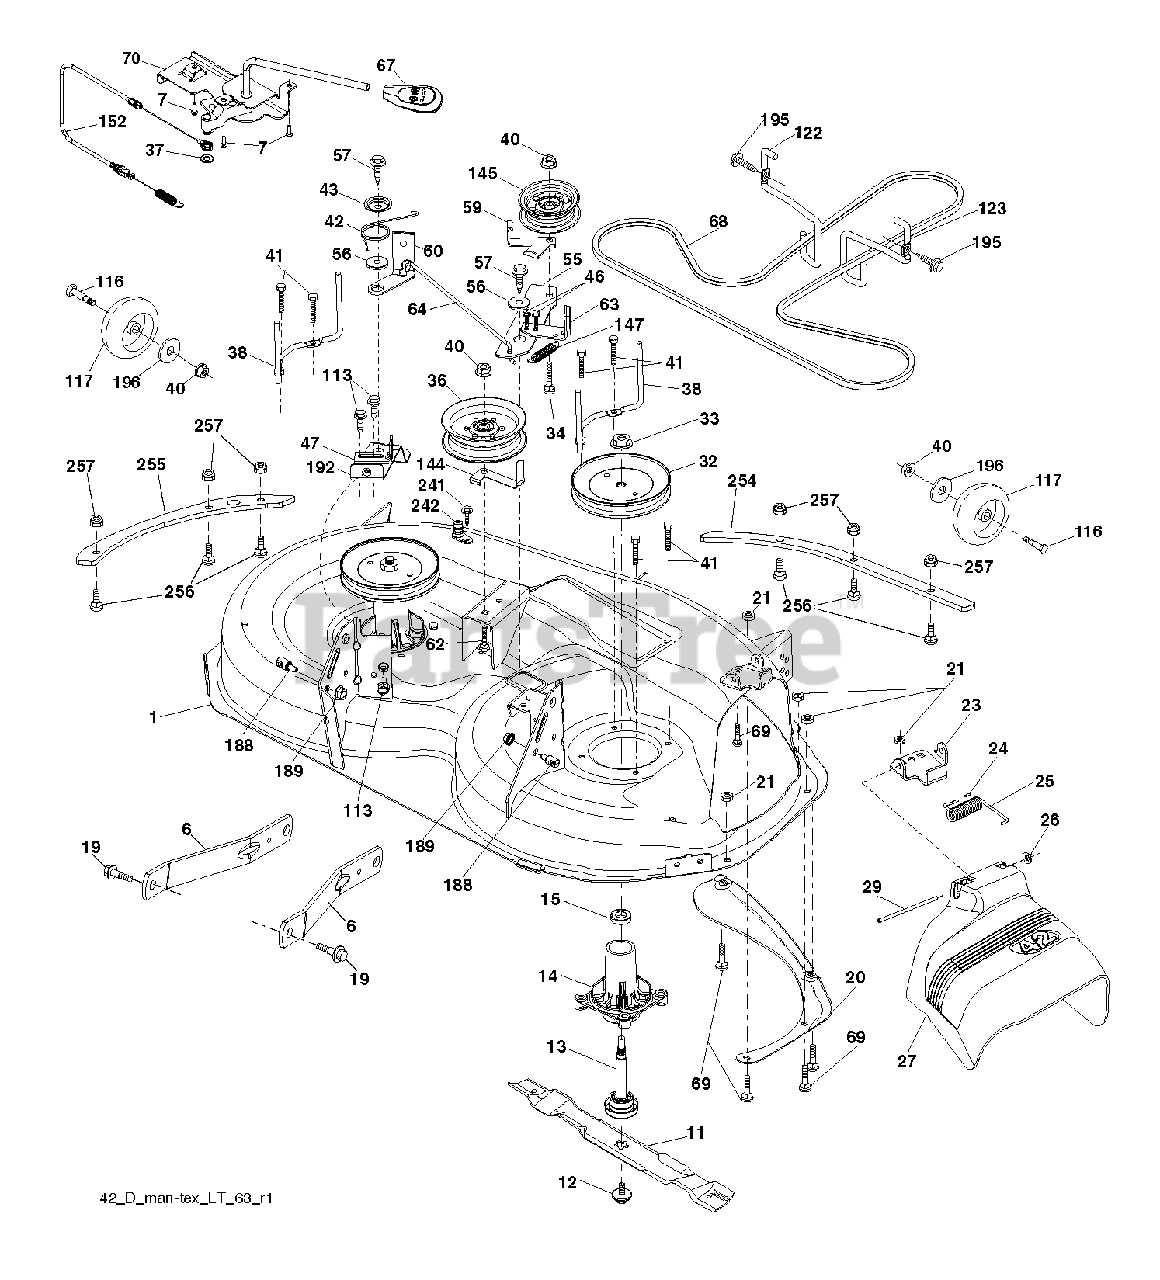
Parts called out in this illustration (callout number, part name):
1	DECK.SVC.42"2GW
6	ARM.SUSPENSION.MOWER.R
7	SCREW.#10 X 0.750.BOS
11	42" HI-LIFT BLADE
12	SCREW.SEMS.7/16-20X1.HEX.HEAD
13	SHAFT.ASM.MDRL.N/GREASE.38
14	HOUSING.MANDREL.4PT.
19	BOLT.SHOULDER
20	BAFFLE.VORTEX
21	LOCKNUT
23	BRKT.DEFLECTOR.38"2005+
24	CAP-SLEEVE LT
25	SPRING.TORSION.DEFLECT
26	NUT PUSH M
27	SHIELD.DEFLECTOR.MOWER.42"BLAC
29	ROD.HINGE
32	PULLEY.MANDREL.5.438.PD
33	NUT.FLANGE.LOCK.TOP
34	BOLT.3/8-16X1.50
36	PULLEY.IDLER.2006
37	WASHER
38	KEEPER.BELT.MANDREL.PULLEY
40	NUT LOCK FLG 3/8-16 UNC
41	BOLT.HEX.WASHR.HED.313-18X1.19
42	SPRING.TORSION.BRAKE
43	SRPING.TORSION.RETAINE
46	SCREW.1/4-20X5/8
47	BRKT.CLUTCH.CABLE
55	IDLER.ARM.42"
56	SPACER.RETAINER
57	SCREW 3/8-16X1
59	GUARD, BELT
60	ARM BRAKE MOWER
63	ARM BRAKE MOWER
64	LINKAGE.BRAKE.ASM.ZINC
67	HANDLE.CLUTCH.CABLE.LT
68	BELT.DECK.DRIVE.42"
69	BOLT
70	CLUTCH.ASM.MANUAL.YT.PREDATORQ
113	BOLT.5/16HEX.WHS.HD
116	BOLT.SHOULDER.3/8-16X3-5/8.
117	WHEEL. GUAGE RALLY
122	KEEPER BELT ENGINE LH
123	KEEPER BELT RH
144	KEEPER.BELT.MOWER
145	PULLEY.IDLER.48"PRIMARY
147	RETURN SPRING
152	CABLE.MECHANICAL.CLUTCH
188	STUD.FASTNER.W/ANTI-ROTATE
189	NUT LOCK HEX FLANGE 5/16-18
192	BRKT.BRAKE.STAND.LH.
195	SCREW, 3/8-16X3/4
196	WASHER
241	SCREW.TT.#10-32X.5.3/8.FLANGE
242	PORT.WASHOUT
254	PLATES.RENFRC.42DECK.PT431FRNT
255	PLATES.RENFRCE.42DECK.X431SIDE
256	RHSNB, 1/4-20 X 1, GR5
257	RHSNB, 1/4-20 X 1, GR5
